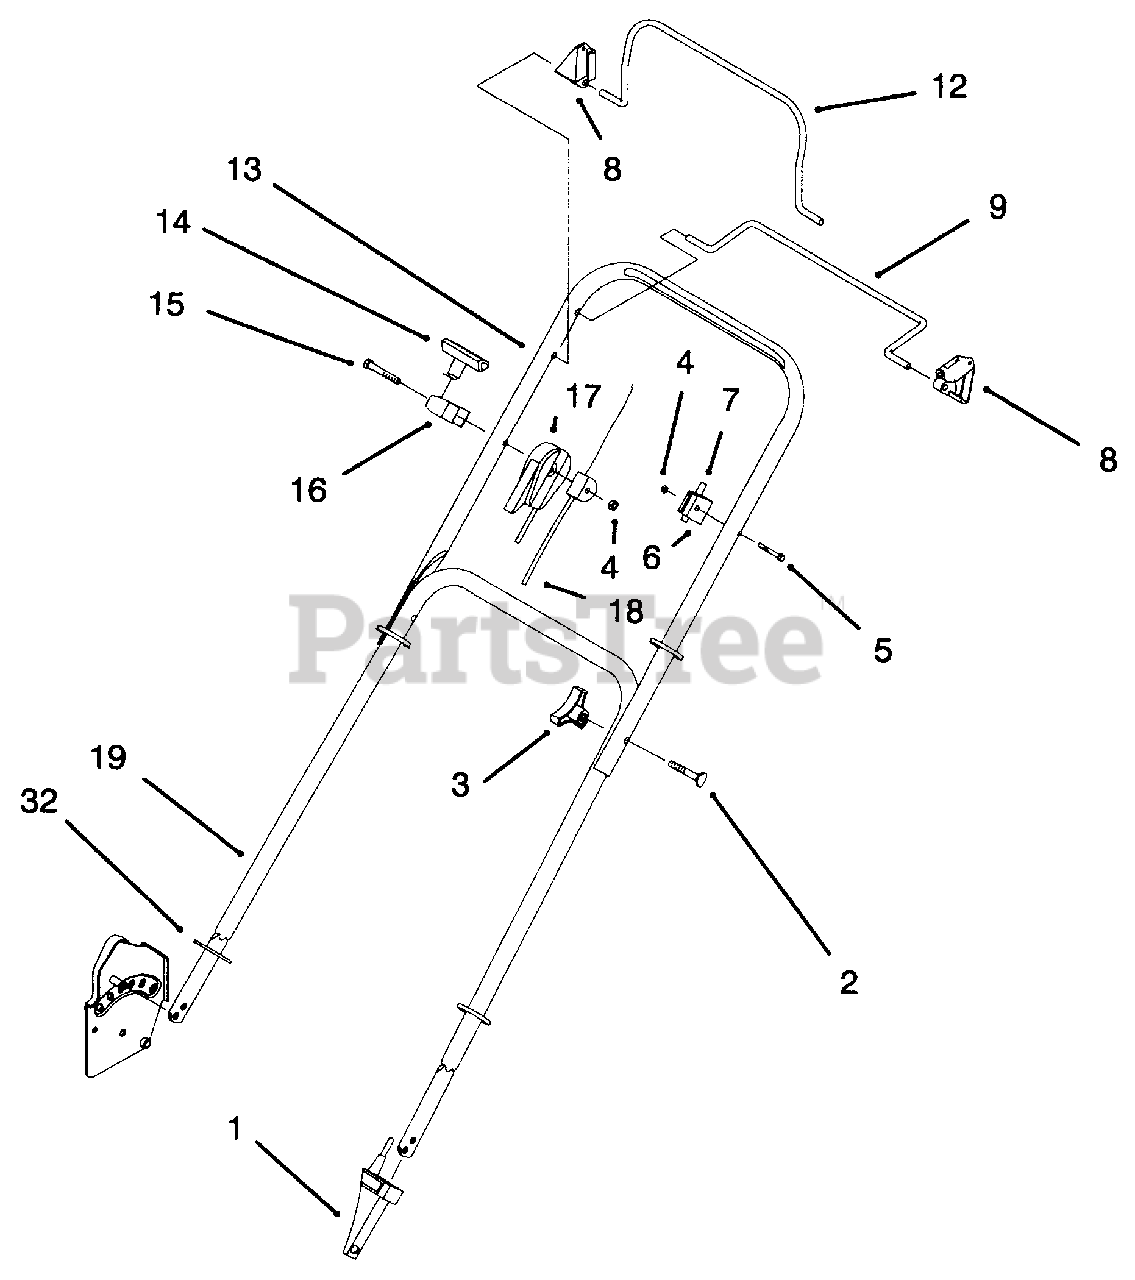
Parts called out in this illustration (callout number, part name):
1	Anchor Cable SP Lower
2	Screw-Handle
3	Knob
4	Nut-Lock
5	Screw-Handle
6	Anchor-Cable SP Upper
7	Cable-Traction
8	Stop-Pivot
9	Bail-SP Control
12	Bail-Flywheel Brake
13	Handle-Upper
14	Handle-Starter
15	Screw-Hex Hd. Cap
16	Guide-Rope
17	Cable-Throttle
18	Cable-Brake Assembly
19	Handle-Lower
32	Guard-Handle
